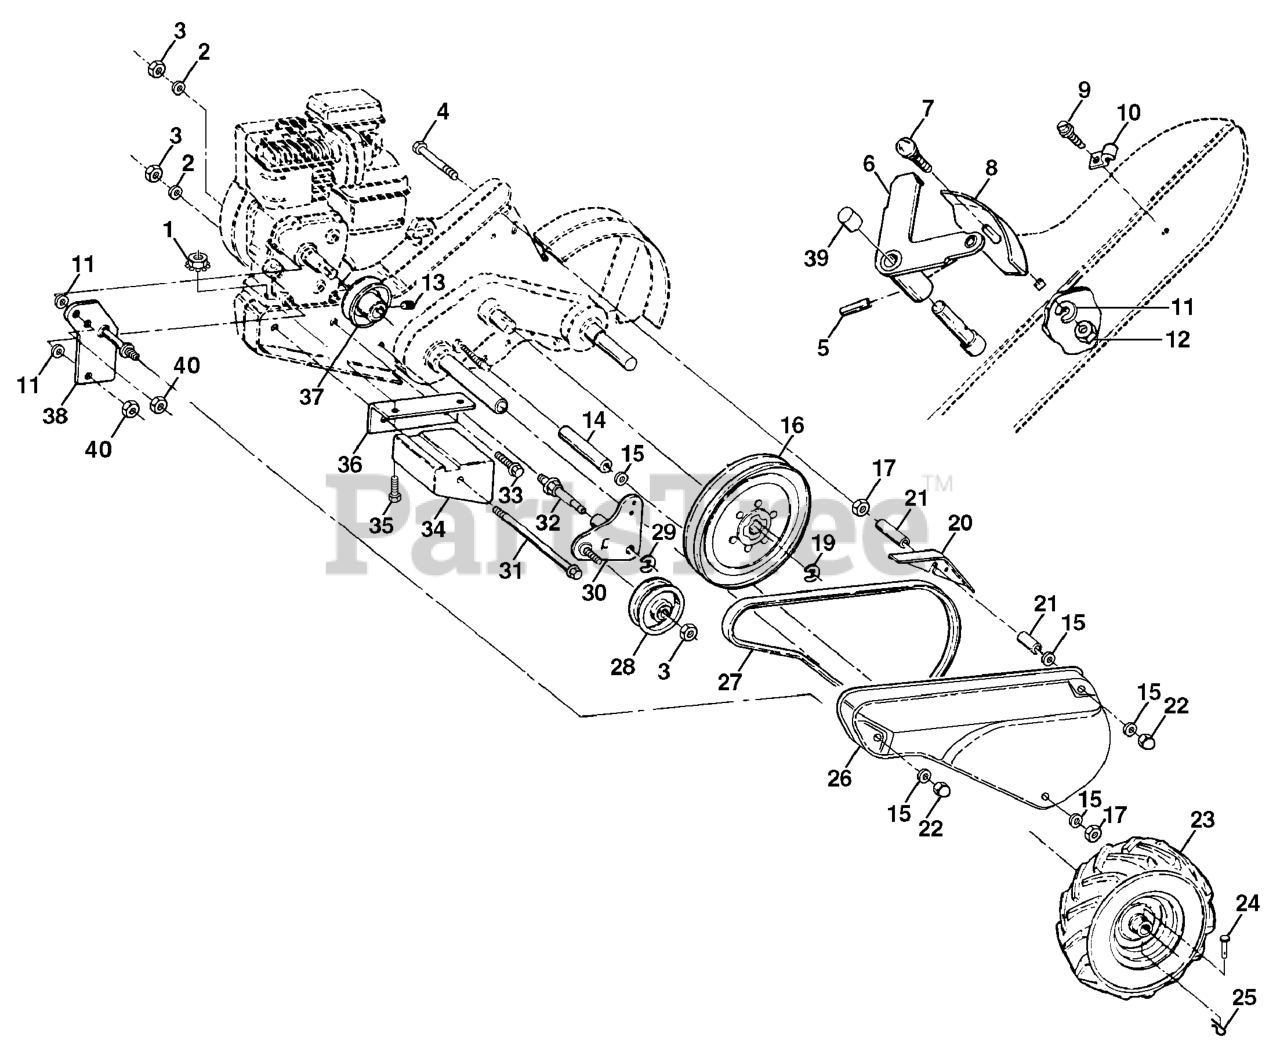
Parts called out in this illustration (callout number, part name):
1	NUT
2	WASHER, LOCK 3/8
3	NUT.HEX.3/8-16UNC
4	Bolt, Hex 5/16-18 x 4-1/4
5	DRIVE PIN
6	LEVER ASM CRT
8	PANEL.INDICATOR.SHIFT.BLACK
9	TAPPING SCREW
10	CONDUIT.CLIP.PLATED
11	LOCKWASHER
12	NUT
15	WASHER
16	SHEAVE 10" CRT
17	NUT
18	SPACER CRT
21	SPACER SPLIT
23	TIRE.13X5-6.CHEVRON.TILLER
23	RIM ASM.6"WHITE.TILLER
23	VALVE STEM LT
24	RIVET,DRILLED
25	RETAINER M
26	BELT GUARD
28	PULLEY-IDLER TI
30	BRACKET ASSY TI
31	BOLT.FIN.HEX.3/8-16UNC
32	SHIFT ARM CRT
33	BOLT
34	COUNTERWEIGHT.LH.CRT
35	BOLT
36	BRACKET LH CRT
37	PULLEY.ENGINE.3".OD
38	BELT GUARD BRKT
39	CAP.PLUNGER.BLACK
40	LOCKNUT.NYLOC.1/4-20
